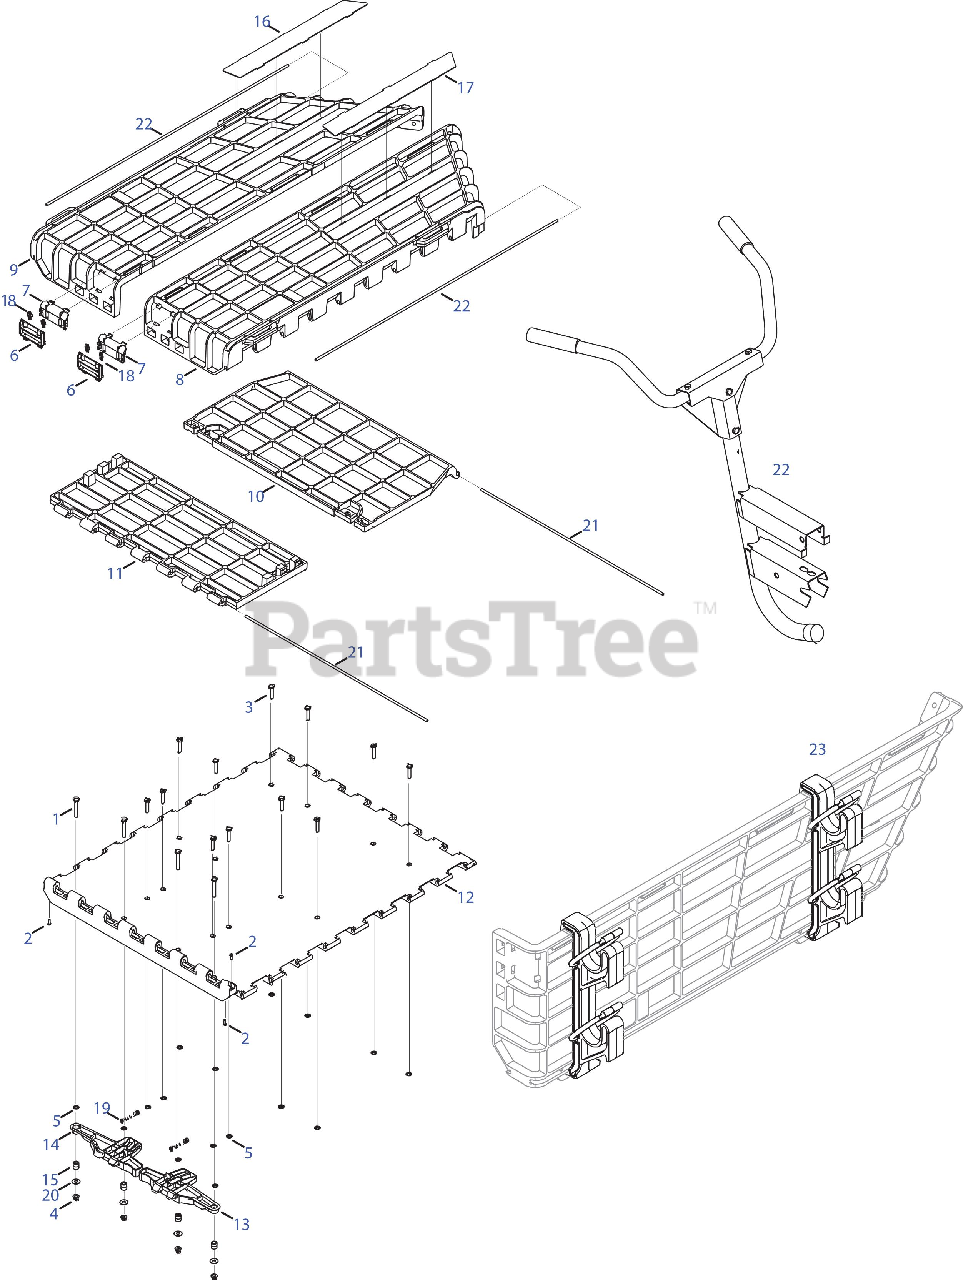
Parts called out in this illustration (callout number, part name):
1	Hex Screw, 5/16-18 x 2.25
2	Hex Washer Screw, #8-16 x .50
3	Hex Screw, 5/16-18 x 1.50
4	Flange Lock Nut, 5/16-18
5	Speed Nut, .3125
6	Panel Latch
7	Panel Latch Retainer
8	LH Side Panel
9	RH Side Panel
10	Tailgate
11	Front Panel
12	Base Panel
13	RH Door Release Lever
14	LH Door Release Lever
15	Lever Spacer, .32 x .63 x .64 LG
16	RH Logo Plate
17	LH Logo Plate
18	Compression Spring, 1.00 x .313
19	Compression Spring, 2.50 x. 480
20	Flat Washer, .349 x .879 x .063
21	Rod, .25 x 27.5
22	Rod, .250 x 36
23	EZ-Stow? Handles
24	EZ-Stow? Toolholders
